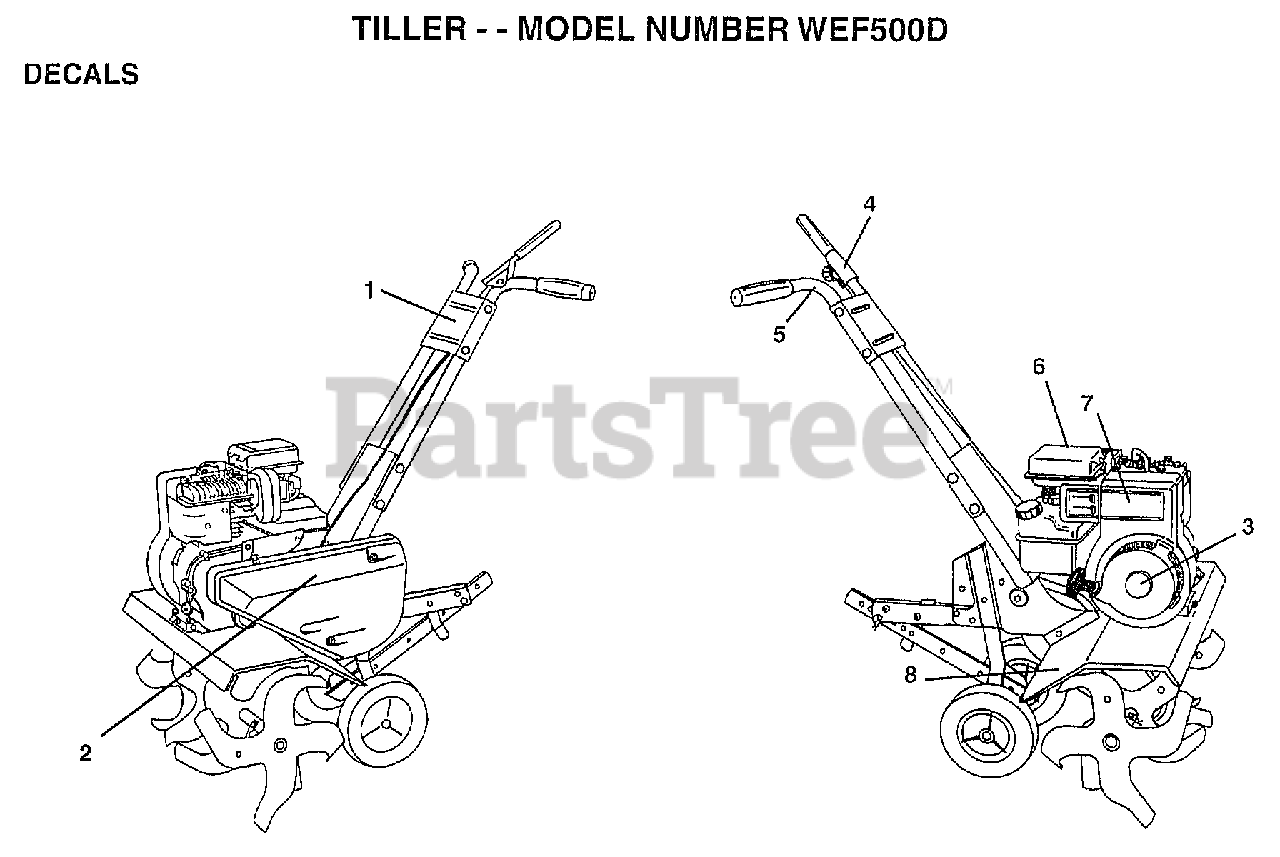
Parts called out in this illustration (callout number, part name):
1	"DECAL PANEL,CTRL"
2	DECAL GUARD BELT
4	DECAL TI
5	DECAL TI
6	DECAL TI
7	DECAL, BRIGGS & STRATTON
